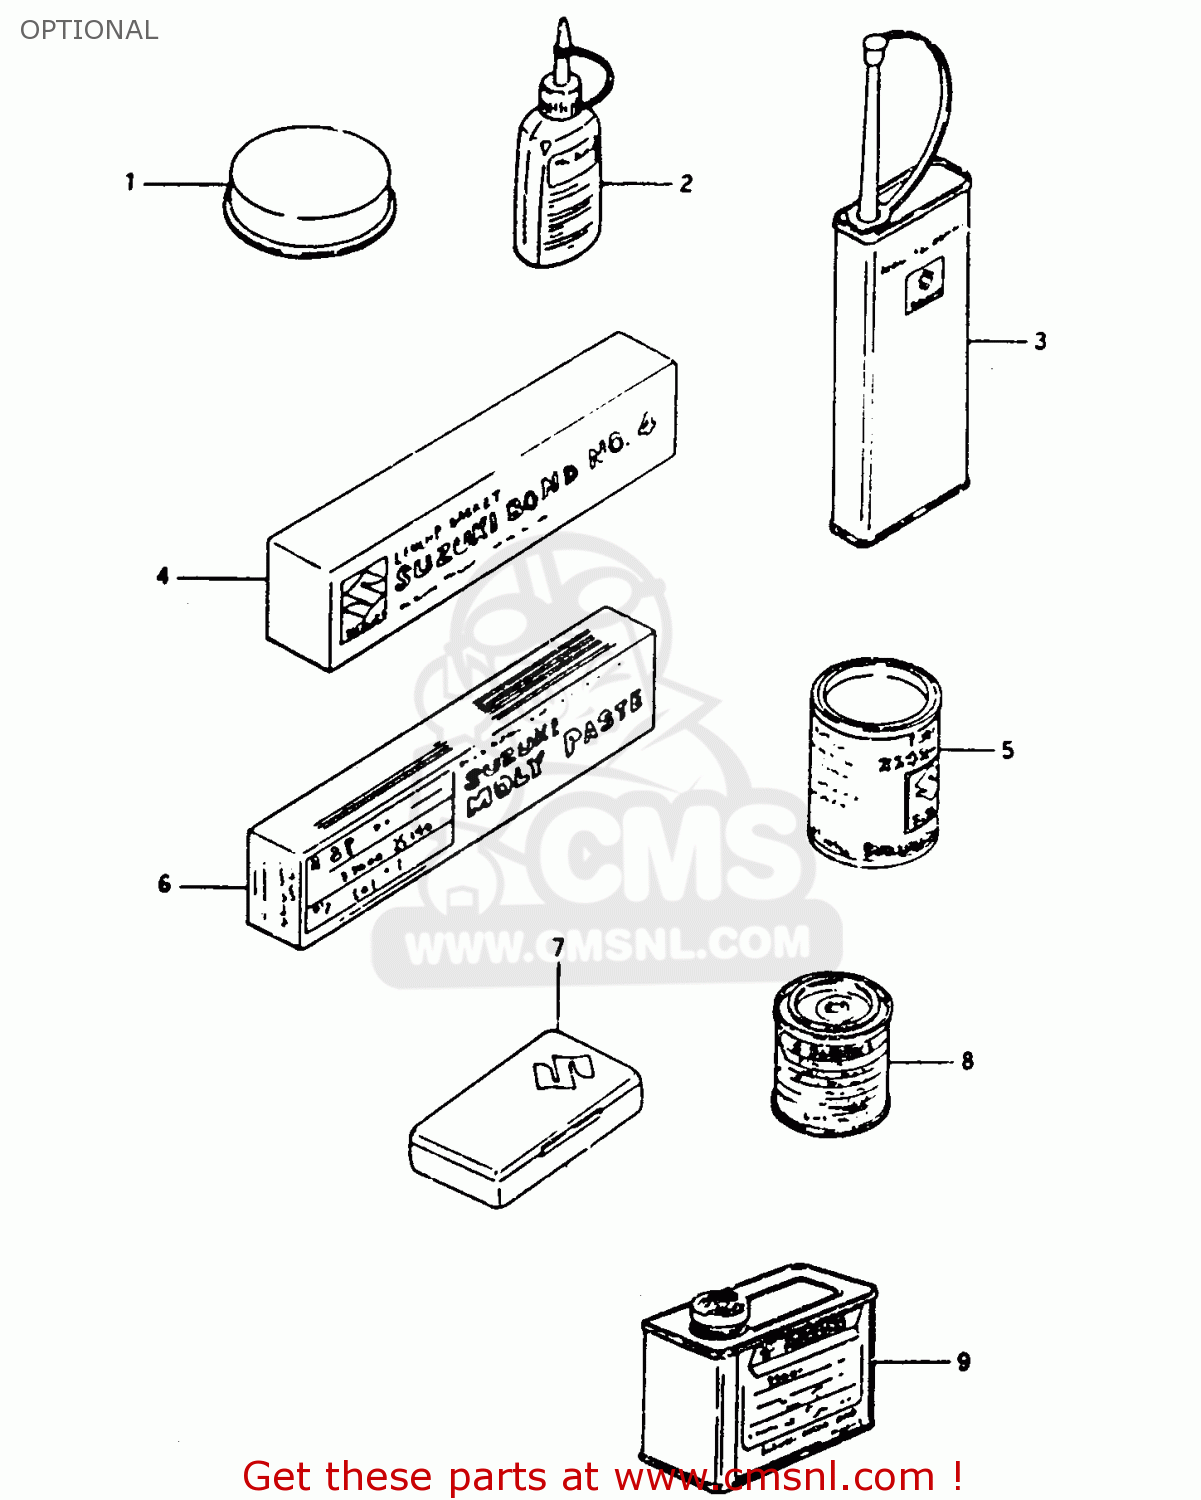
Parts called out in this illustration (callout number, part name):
1	GREASE,PBC FOR BRK PAD 20G
2	THREAD LOCK NO.1342
3	THREAD LOCK NO.1401 CLEAR 200G
4	BOND 1104
5	GREASE(C)EP2 LITHIUM 150G
6	SUZUKI MOLY PASTE
7	TUBE REPARING TOOL
8	PAINT,BLACK
9	PAINT (BLACK)
